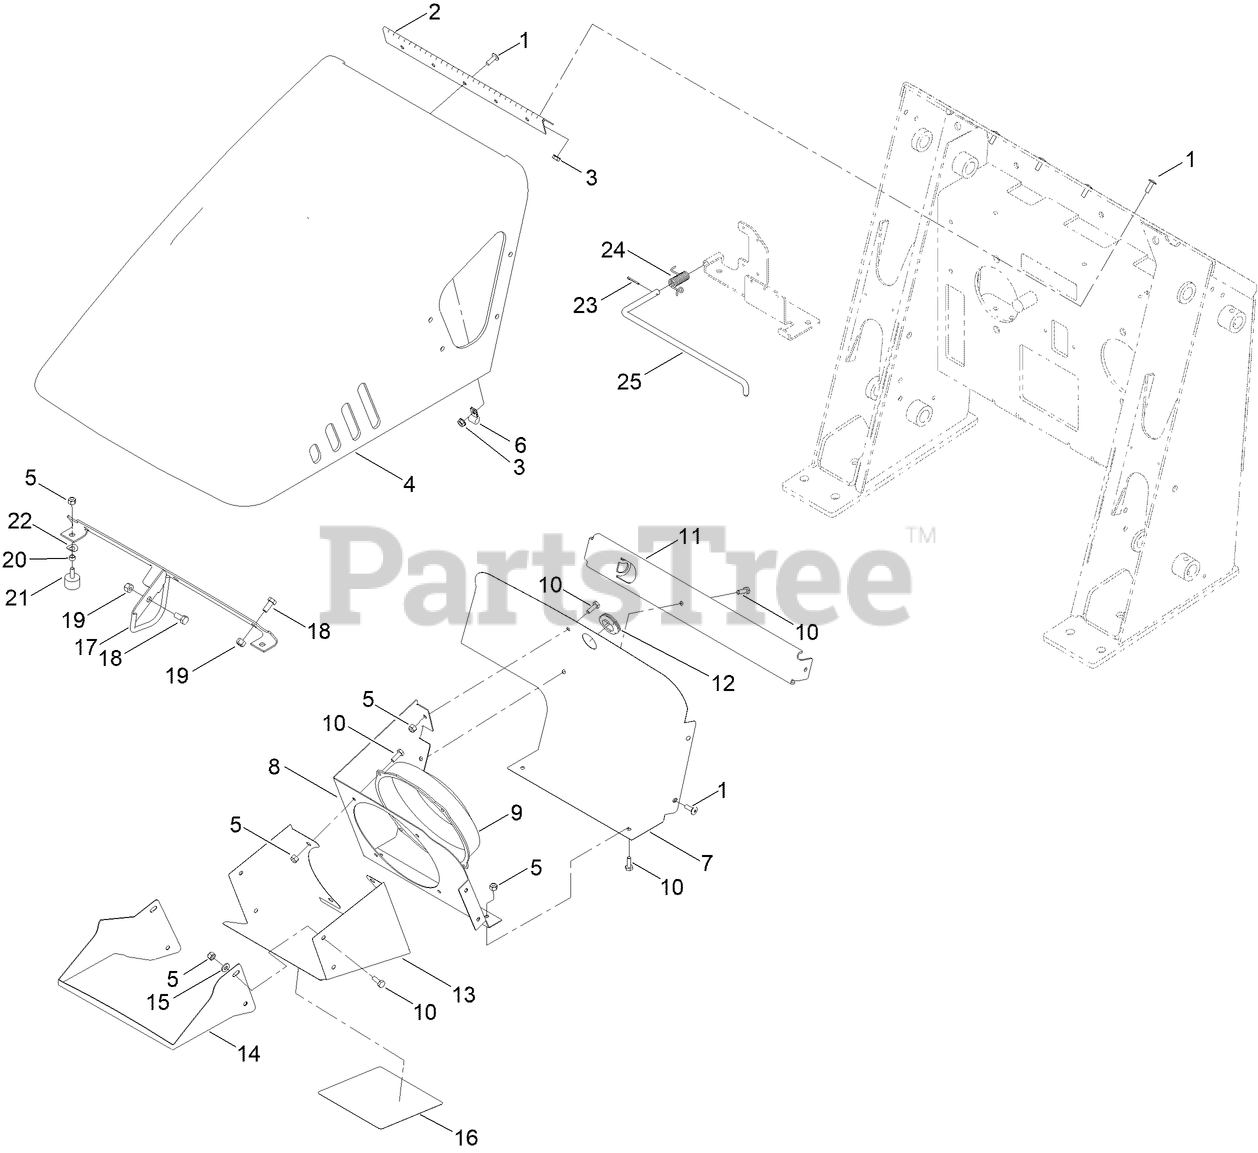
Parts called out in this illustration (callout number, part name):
1	SCREW-HEAD, TRUSS
2	HINGE-HOOD
3	NUT-HF
5	NUT-LOCK, NI
6	CLAMP
7	BRACKET-FAN, BACK
8	BRACKET-FAN, BACK
10	SCREW-HH
11	BRACKET-SUPPORT, HOOD
12	GROMMET
13	SHROUD-FAN
14	SHROUD-FAN, FRONT
15	WASHER-FLAT
16	DECAL-SERVICE TX427 DE
16	DECAL-SERVICE TX427 ES
16	DECAL-SERVICE TX427 FR
16	DECAL-SERVICE TX427 IT
16	DECAL-SERVICE TX427 NE
16	DECAL-SERVICE TX427 PL
16	DECAL-SERVICE TX427 RU
16	DECAL-SERVICE TX427 SK
17	LATCH-ROD
18	SCREW-HH
19	NUT-LOCK, NI
20	SPACER
21	BUMPER
22	WASHER-SPRING
23	PIN-COTTER
24	SPRING-TORSION
25	ROD-SUPPORT, HOOD
